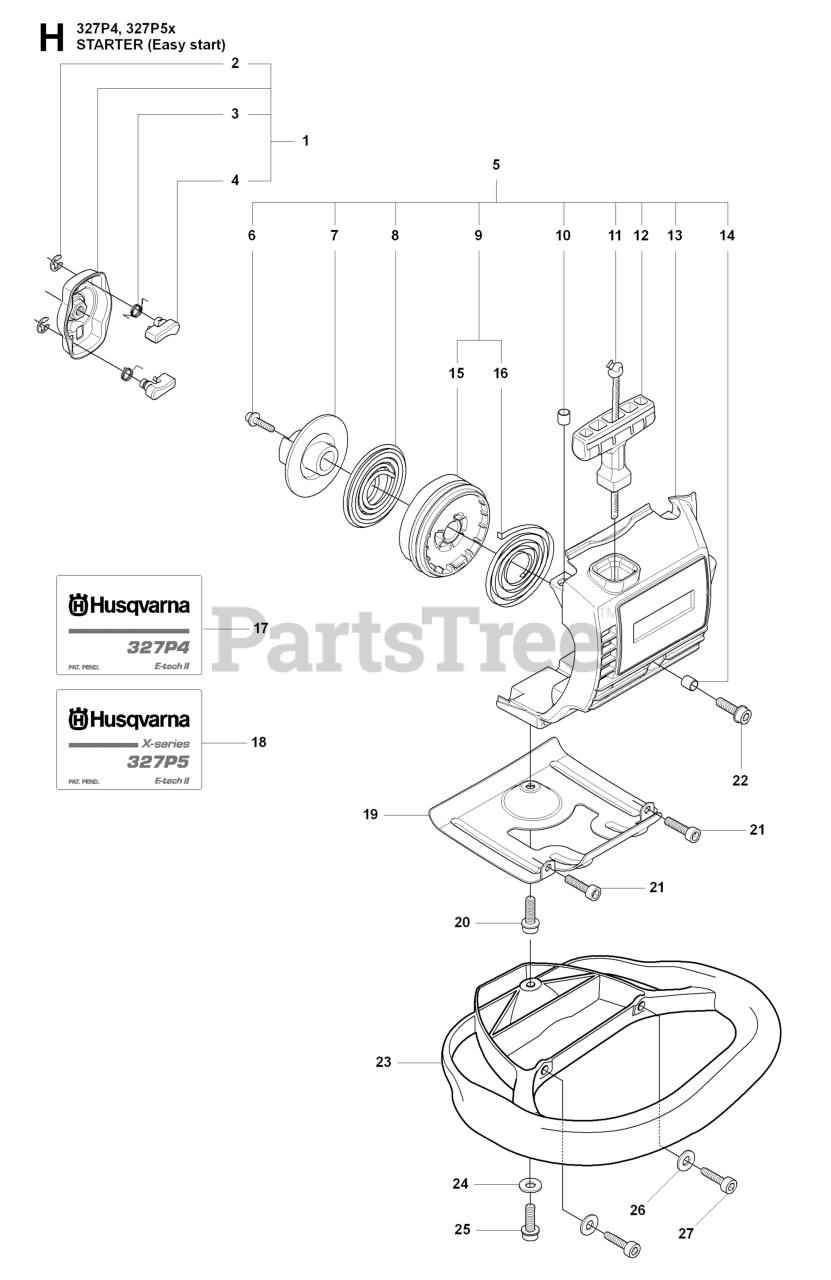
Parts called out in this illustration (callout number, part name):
1	STARTER PAWL BRIDGE
4	STARTER PAWL
5	RP STARTER ASSY
7	DRIVER PULLEY
8	SPRING - DRIVER
9	STARTER PULLEY
10	SPACING SLEEVE
11	STARTER ROPE
12	STARTER HANDLE
13	RP STARTER HOUSING
14	SPACING SLEEVE
15	STARTER PULLEY
17	LABEL 327P4
18	LABEL
20	SCREW
22	SCREW
